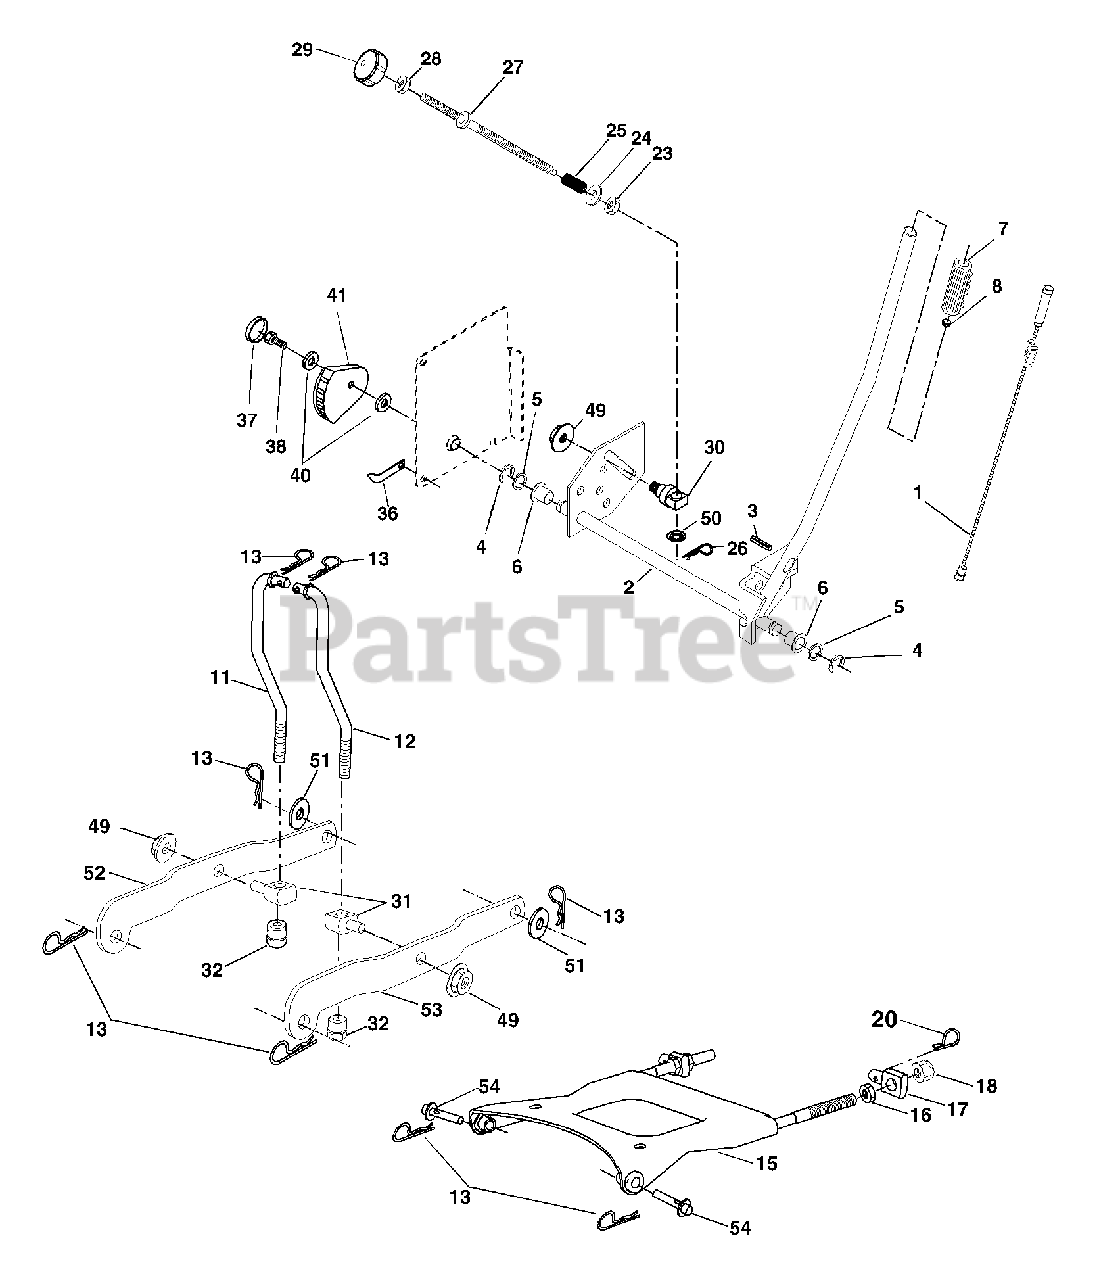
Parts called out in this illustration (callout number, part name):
1	Wire Asm Inner/Sprg W/plunger
2	Shaft Asm Lift RH w/Inf
3	Pin Groove
4	E Ring #5133-62
5	Washer 21/32 X 1 X 21 Ga
6	Bearing Nylon Blk 629 Id
7	Grip Handle
8	Button Plunger
11	Link Lift LH
12	Link Lift RH
13	Retainer Spring
15	Plate Asm. Suspension Front
16	Nut Jam Hex 1/2-13 Unc
17	Trunnion Front Susp.
18	Nut Lock w/Wsh 1/2-13unc
20	Retainer Spring
23	Nut Special
24	Washer 13/32 X 5/8 X 16 Ga
25	Spring
26	Retainer Clip
27	Rod Adj Lift
28	Nut Hex Jam 3/8-16 Unc
29	Knob Inf 3/8-16 Unc Blk W/sym
30	Trunnion Infin Height
31	Trunnion Susp. Arm
32	Nut Lift Link 7/16-20
36	Pointer Height Indicator
37	Plug Hole Blk 1.485/1.515 Dia.
38	Screw 5/16-18 x 1
40	Washer 11/32 x 1-1/2 10 Ga.
41	Indicator Height STLT
49	Nut Hex Flange Lock
50	Nut PUsh Phos & Oil
51	Washer 17/32 x 7/8 x 16 Ga.
52	Arm Susp. Rear LH
53	Arm Susp. Rear RH
54	Pin
